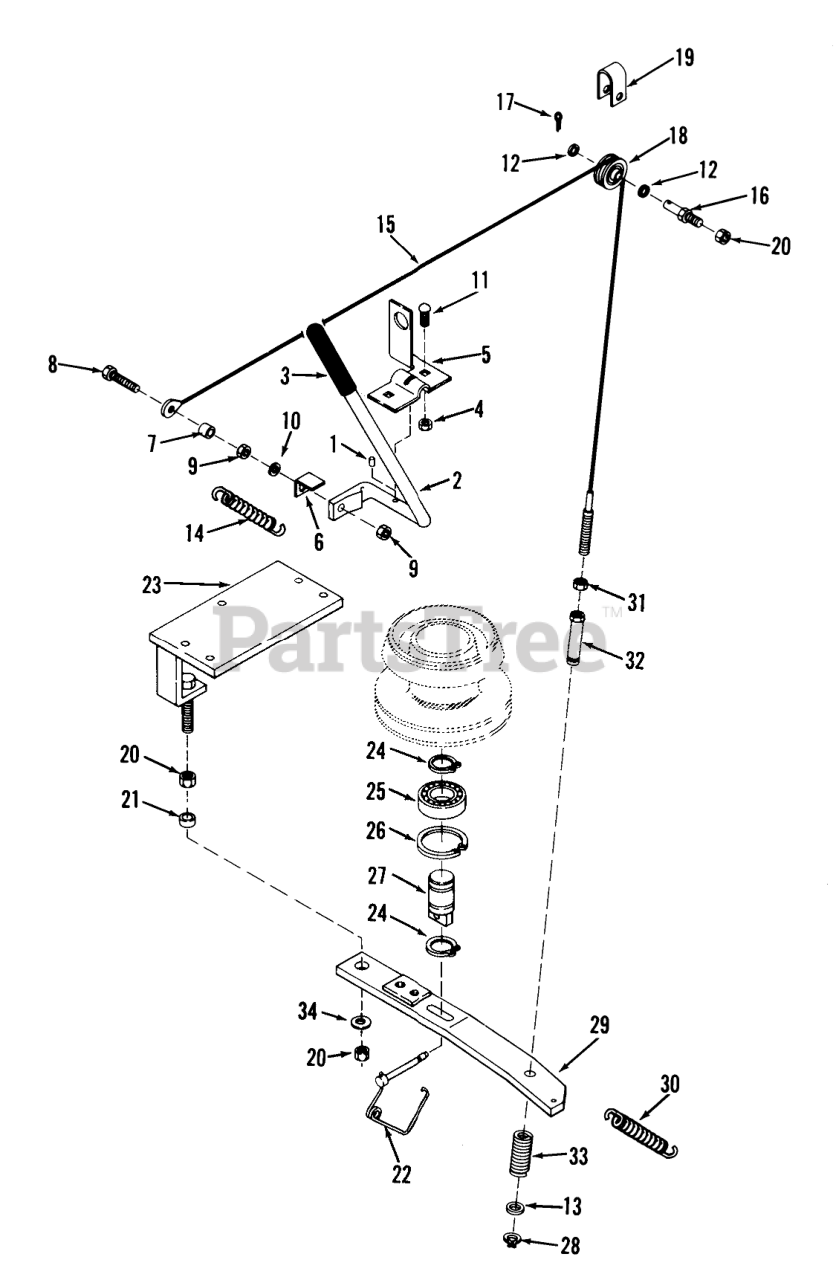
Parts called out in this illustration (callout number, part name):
1	SPIROL PIN
3	GRIP
13	Washer
14	SPRING-EXTENSION
19	STRAP-CABLE
21	SPACER-CLUTCH BAR
27	SHAFT-CLUTCH HSG
33	SPRING-CLUTCH
